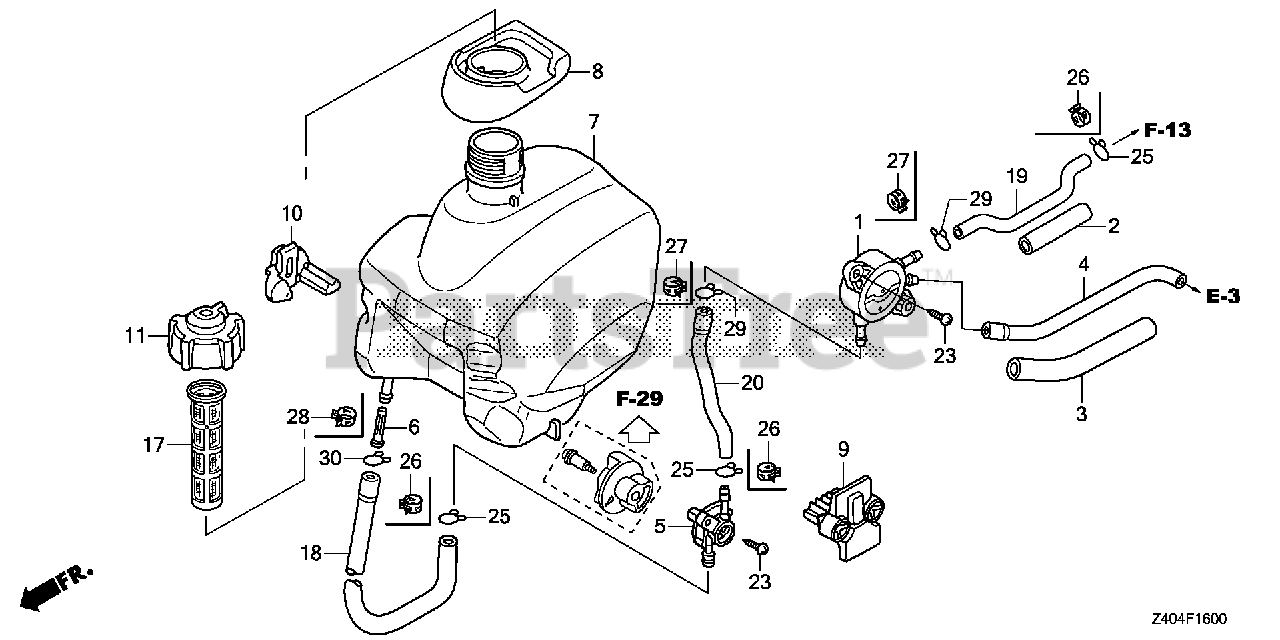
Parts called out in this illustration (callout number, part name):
1	PUMP ASSY., FUEL (MSDS)
2	RUBBER A, SUPPORTER
3	RUBBER B, SUPPORTER
4	TUBE, DIAPHRAGM
5	PETCOCK ASSY.
6	FILTER, FUEL
7	TANK, FUEL (FOR U.S.A.)
8	SEAL, FUEL FILLER NECK
9	RUBBER R, TANK MOUNTING
10	RUBBER L, TANK MOUNTING
11	CAP ASSY., FUEL TANK
17	FILTER, FUEL
18	TUBE, FUEL TANK (FKM)
19	TUBE A, FUEL (FKM)
20	TUBE B, FUEL (FKM)
23	SCREW, TAPPING (5X20) (PO)
26	CLAMP, TUBE (D8)
27	CLAMP, TUBE (D8.5)
28	CLAMP, TUBE (D10.5)
